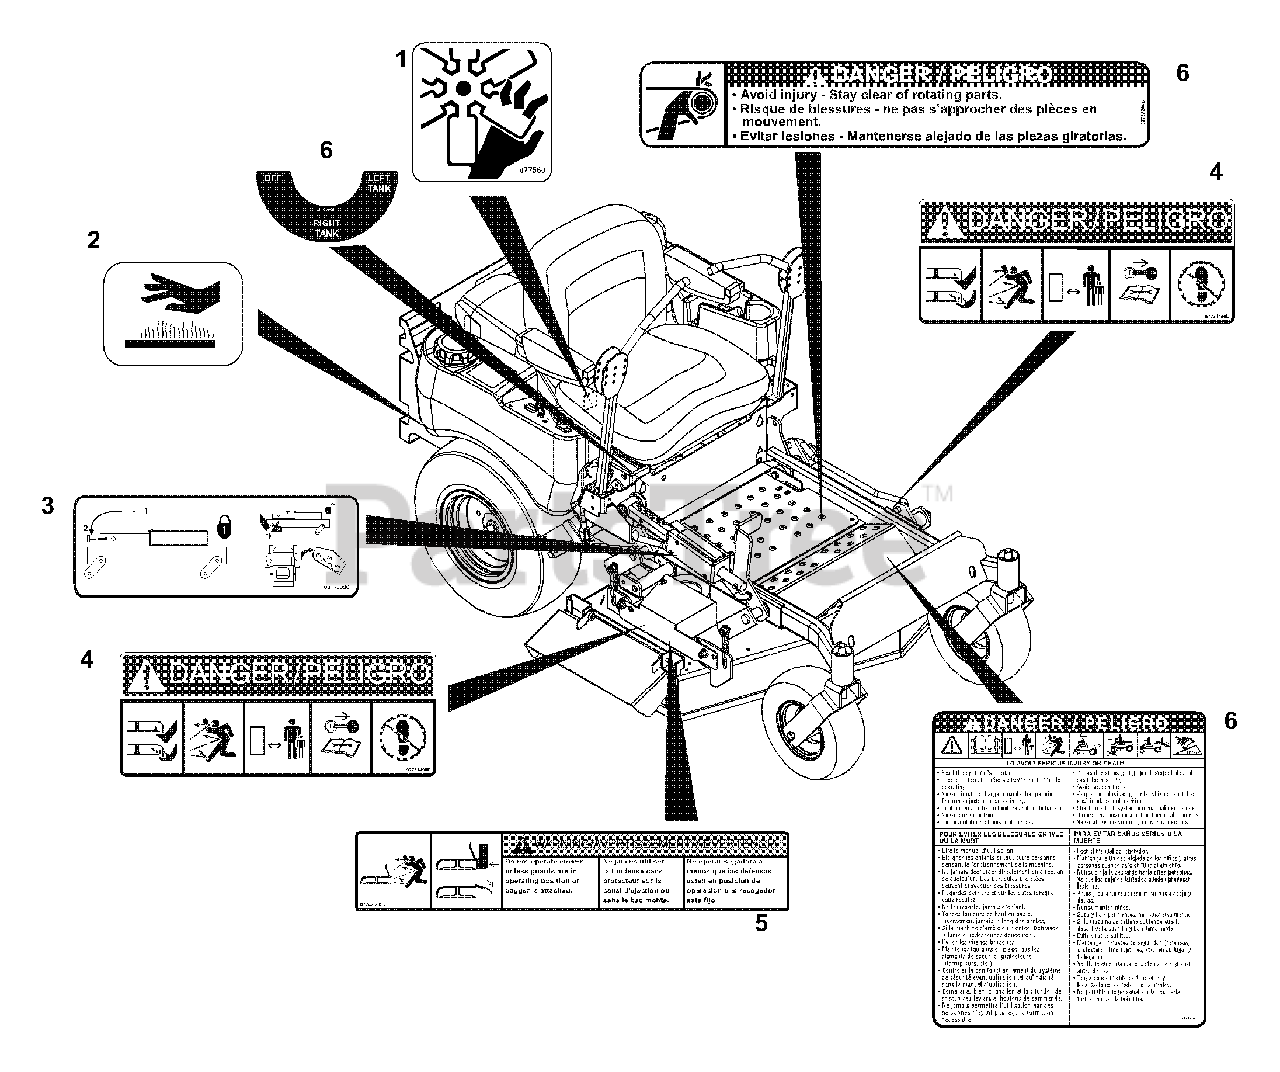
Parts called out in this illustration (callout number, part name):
1	DECAL, DANGER FAN
2	DECAL, HOT SURFACE
3	DECAL, DECK SERVICE
4	DECAL, MOWER PAN DANGER
5	DECAL, WARNING
6	SET-DECAL, COMMON DANGER/FUEL
